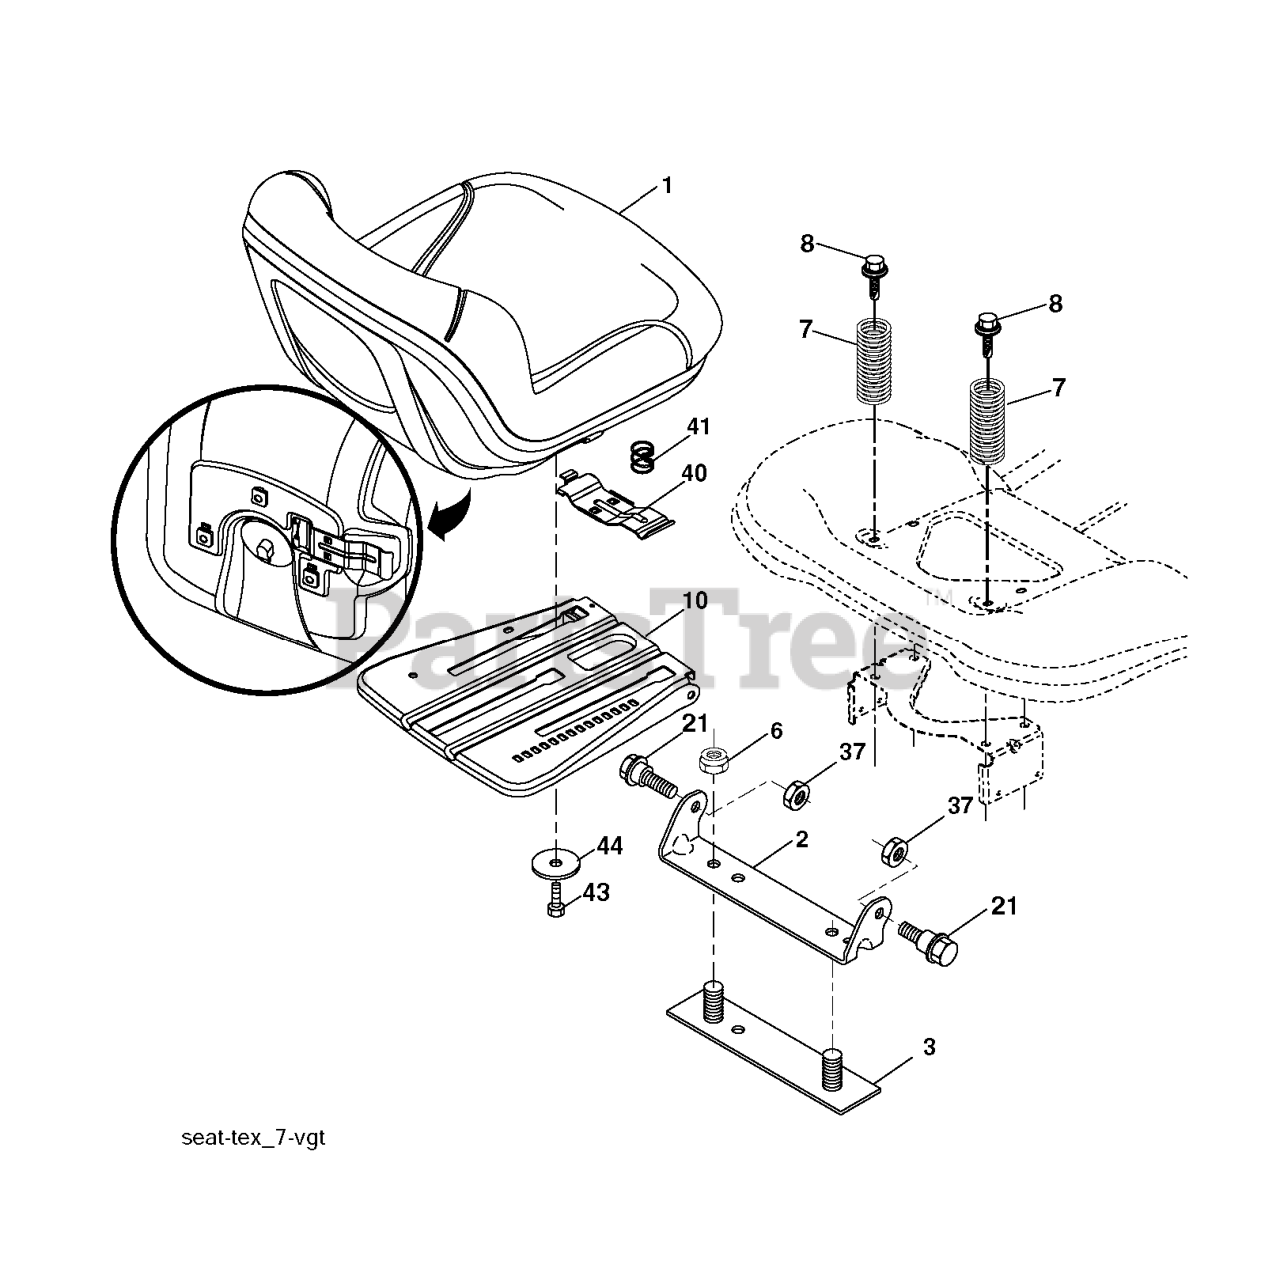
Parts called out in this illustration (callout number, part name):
1	SEAT.TH130.GRY.MILSCO.
2	BRKT.PIVOT.FENDER
3	STRAP
6	NUT
7	SPRING COMPRESSION
8	BOLT.5/16-18UNCX3/4 W/SEMS.BLK
10	PAN.ASM.SEAT.3PT
21	BOLT.SHOULDER.5/16-18
37	NUT.71038.31-18.HEX.NYLOCK
40	HANDLE.SLIDE.SEAT.TEX.BLACK
41	SPRING.LATCH.SEAT.TEX
44	WASHER 13/32 X 2-3/8 X 12GA
